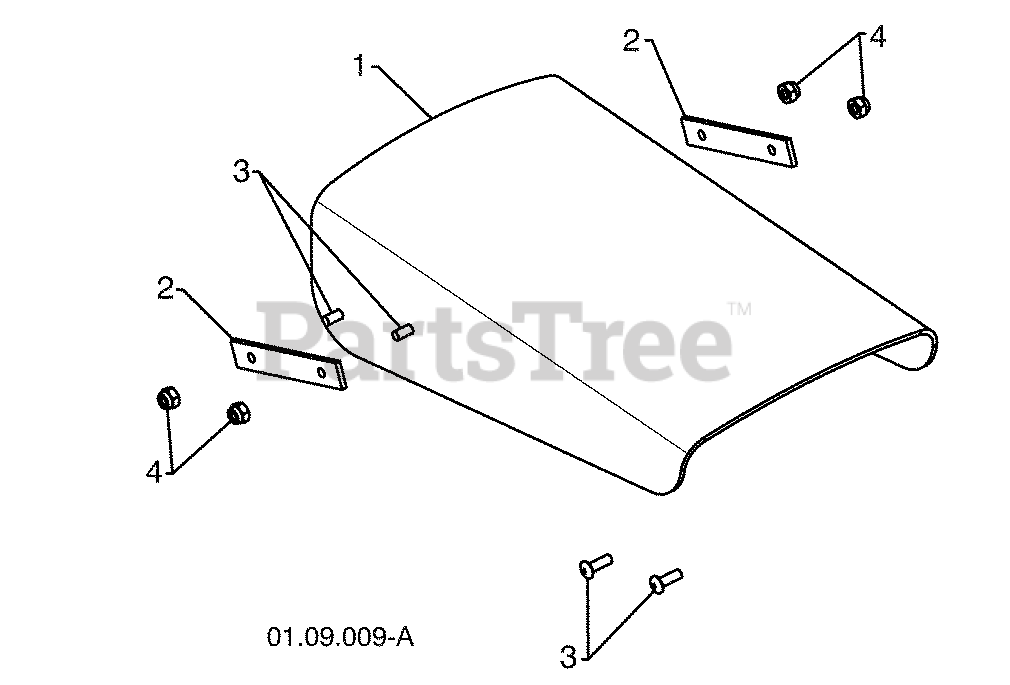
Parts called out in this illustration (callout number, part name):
1	SHIELD DEFLECTOR
2	STRAP
3	SCREW 8-32 X .50
